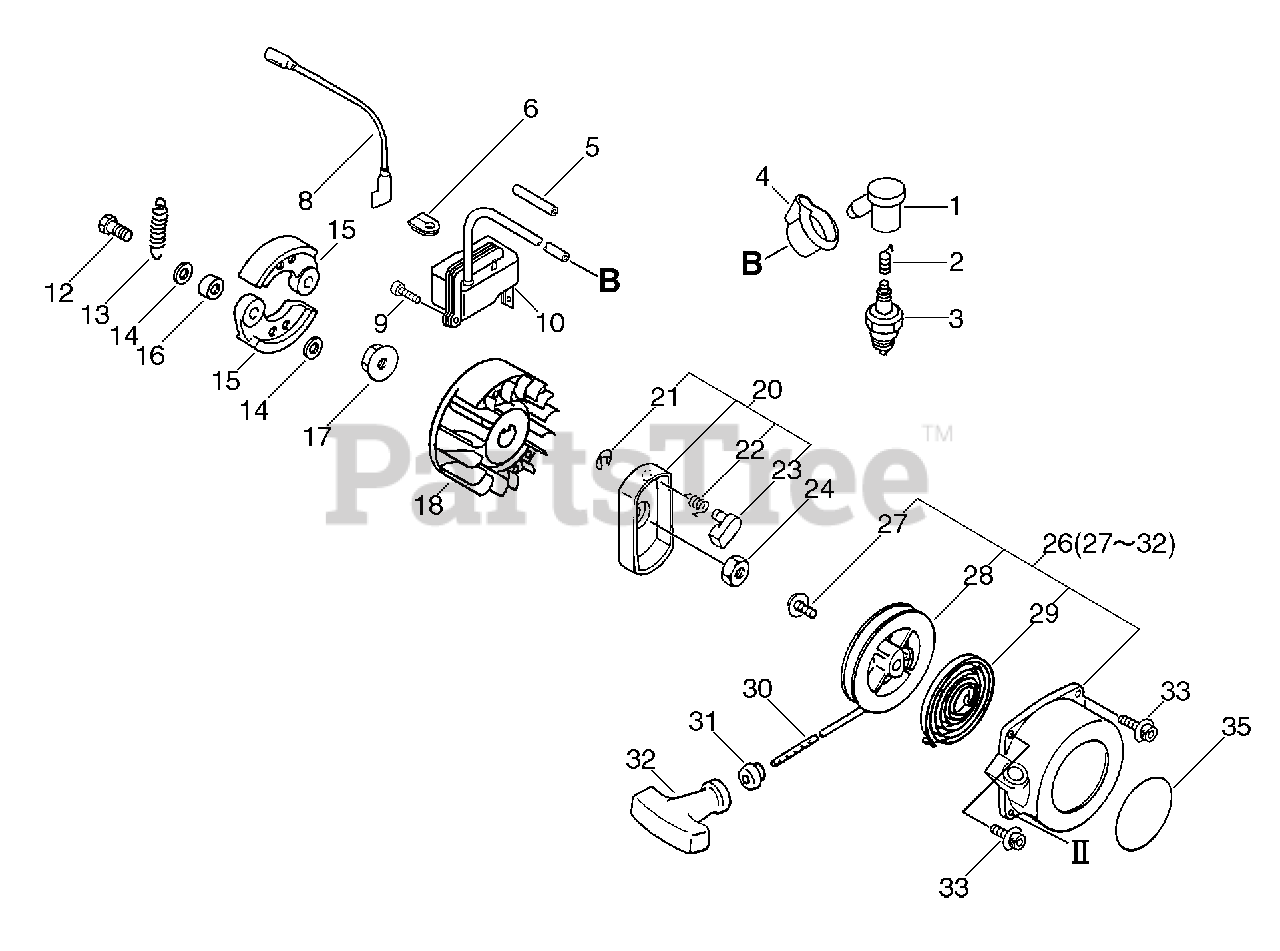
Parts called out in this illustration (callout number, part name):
1	CAP, SPARK PLUG
2	TERMINAL, SPARK PLUG
3	SPARK PLUG - RCJ6Y
4	COVER, DUST
5	TUBE, INSULATOR 7×8.6×55
8	LEAD 170 MM
9	BOLT 5×20
10	COIL, IGNITION
12	BOLT, CLUTCH
13	SPRING, CLUTCH
14	WASHER, CLUTCH
15	SHOE, CLUTCH
17	NUT, FLANGE 10×1.25
18	ROTOR
20	PULLEY ASSY
21	E-RING 4
22	SPRING, RETURN
23	PAWL, STARTER
24	NUT 8×1.25
26	STARTER ASSY, RECOIL
28	REEL, ROPE
29	SPRING, RECOIL
30	ROPE, STARTER 3.8×1150
31	GUIDE, ROPE
32	GRIP, STARTER
33	BOLT 5×20
35	LABEL, ECHO
